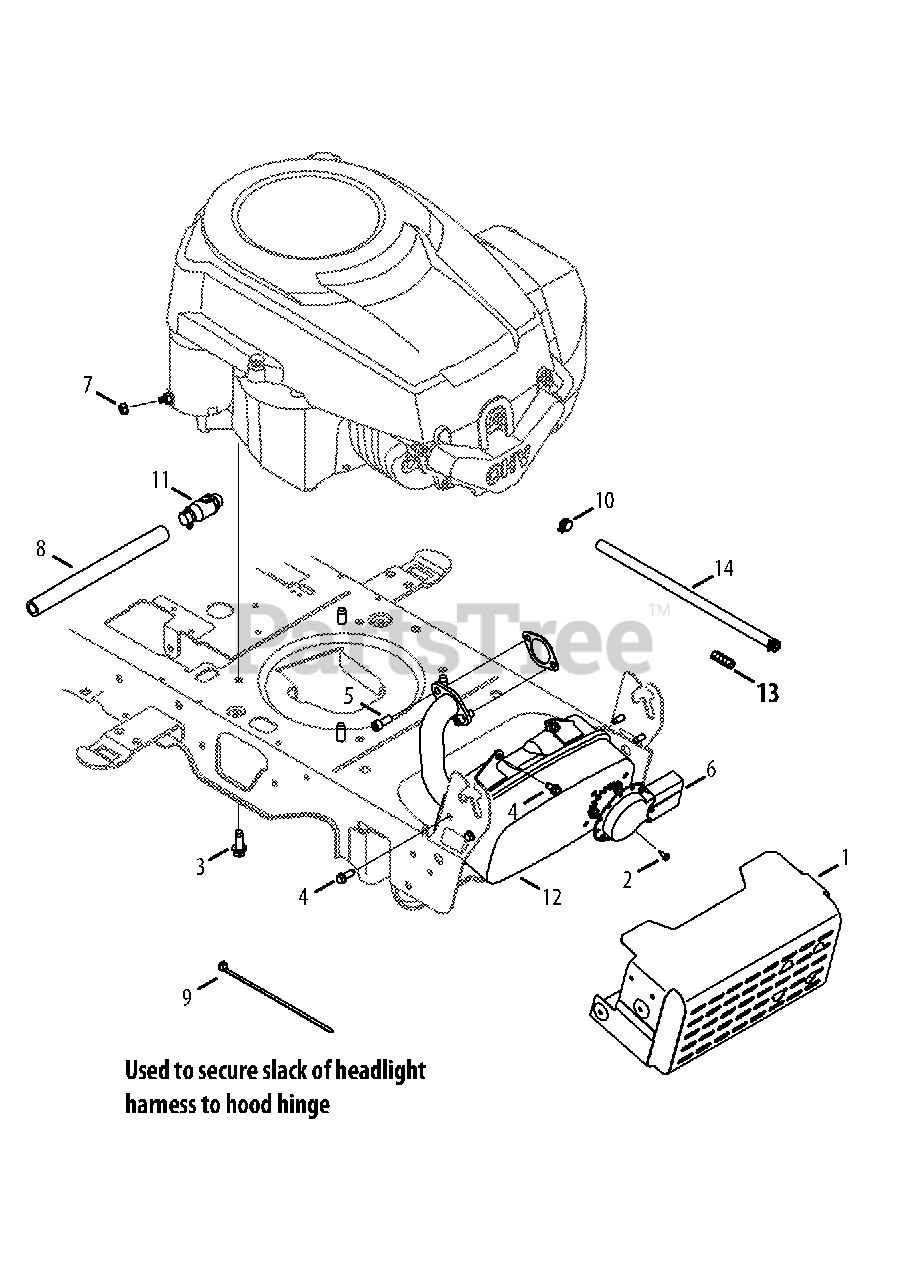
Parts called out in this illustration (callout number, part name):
1	Muffler Shield Assembly
2	Screw, Indented Washer, #8-18:0.500
3	Taptite Screw, 3/8-16:1.000
4	Taptite Screw, 1/4-20:0.500
5	Socket Head Screw, 5/16-18:.750
6	Long Muffler Deflector
7	Sems Nut, 1/4-20
8	Extension Hose, Oil Drain
9	Cable Tie, 3/16 x .05 x 7.4
10	Hose Clamp, .490 DIA.
11	Oil Drain
12	Muffler, Kohler
13	Hose, Vent
14	Fuel Hose
